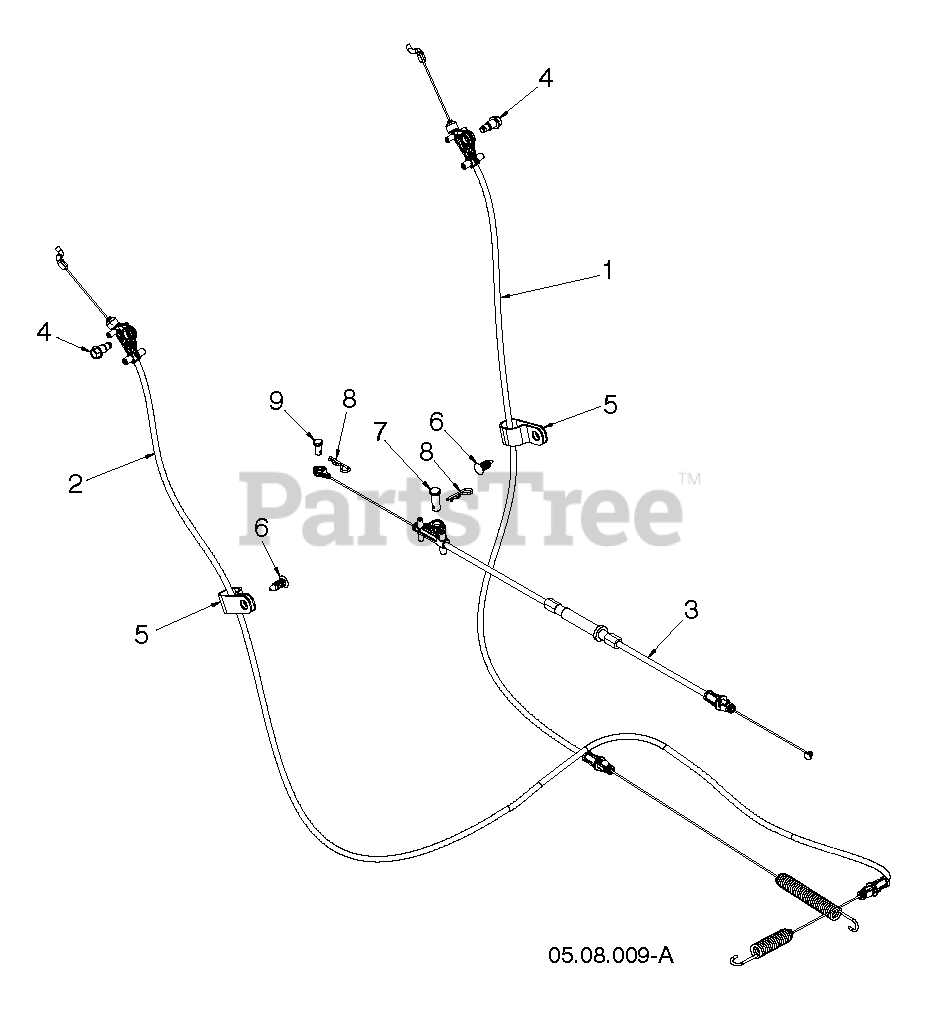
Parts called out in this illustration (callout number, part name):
1	CABLE.CONTROL.DRIVE.DSST.OPP
2	CABLE.CONTROL.AUGER.DSST.OPP.M
3	RB CABLE.CNTRL.SPEED.DSST.OPP
4	BOLT SHOULDER_1/4-20_TRILOB
5	CLIP.CABLE.BLK
6	FASTENER.PUSH.O.250X0.783
7	PIN CLEVIS 5/16X.875
8	HAIRPIN.SOFT.ZINC.059X1.125
9	PIN CLEVIS .25 X .31
